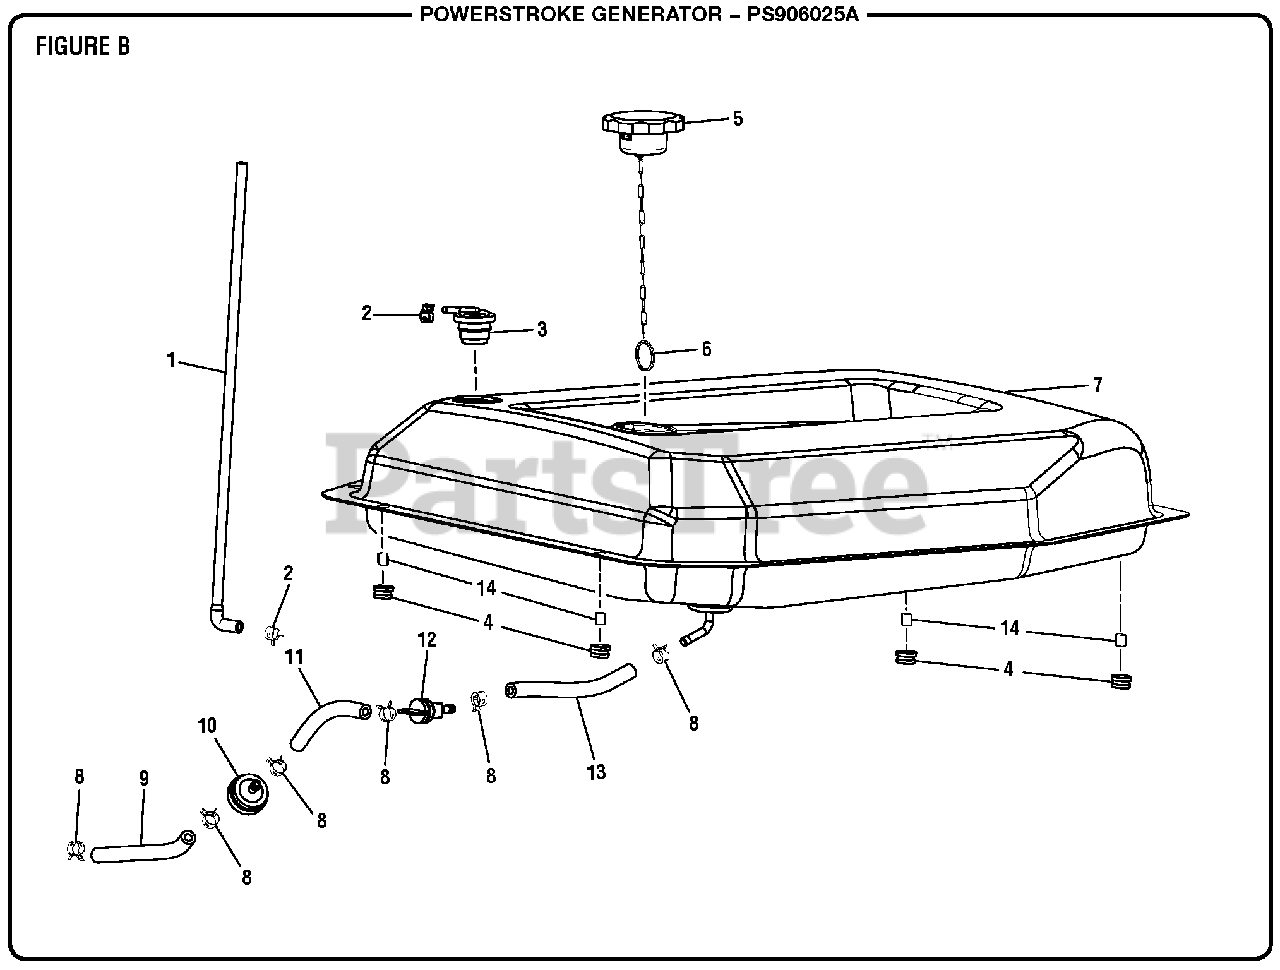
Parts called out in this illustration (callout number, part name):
1	Vapor Hose
2	Fuel Line Clamp (7/16 in.)
3	Fuel Tank Vapor Vent
4	Spacer (Fuel Tank Isolator)
6	Ring Clip
7	Fuel Tank
8	Fuel Line Clamp (1/2 in.)
9	Fuel Line (6.4 mm x 72 mm)
10	Fuel Filter
11	Fuel Line (90 mm)
12	Fuel Shut Off Valve
13	Fuel Line (6.4 mm x 72 mm)
14	Bushing (Fuel Tank Isolator)
